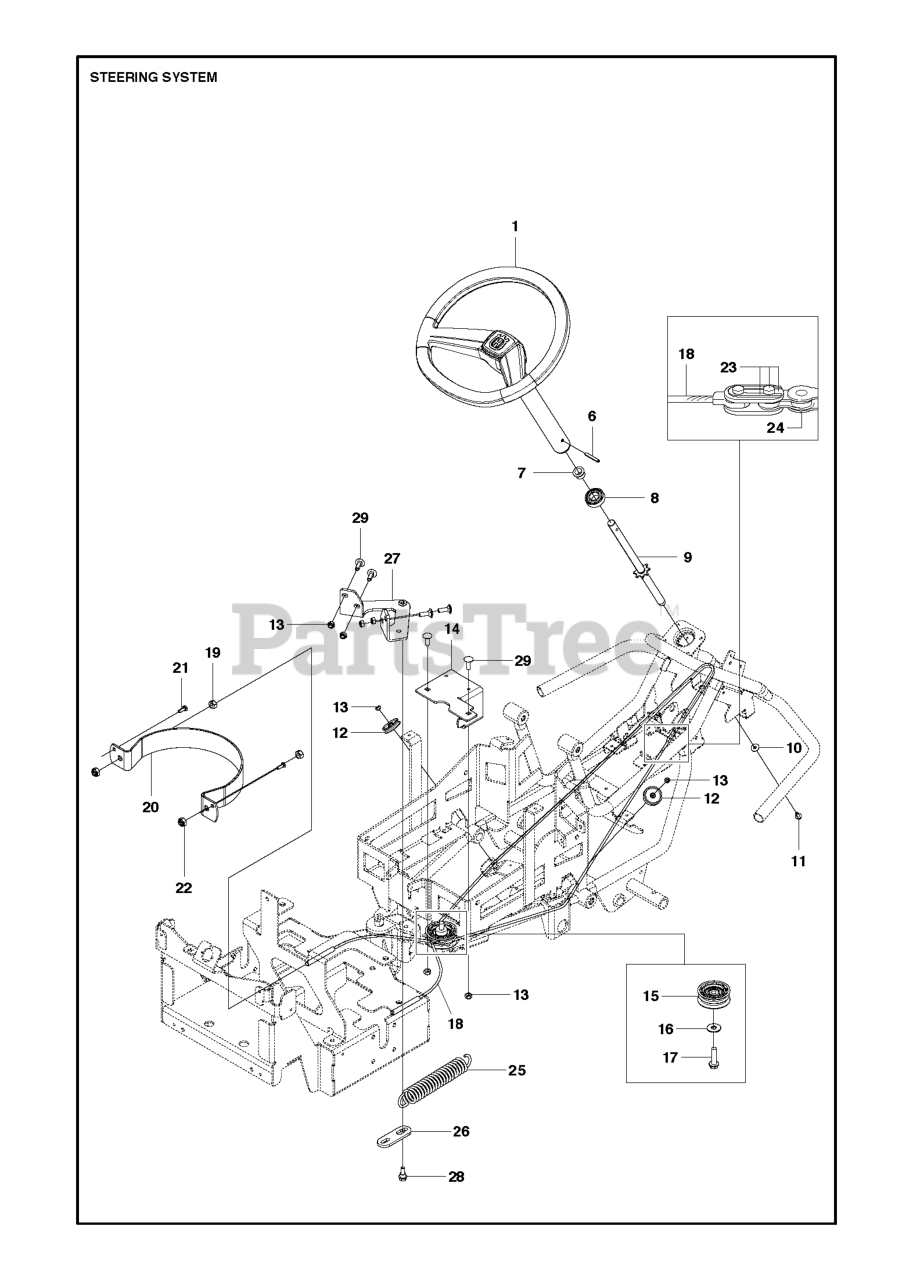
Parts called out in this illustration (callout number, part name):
1	STEERING SYSTEM
8	BALL BEARING 6004-2RS1
9	STEERING ROD
10	WASHER - 26X6.5X1.6
11	SCREW EHHFM
13	LOCKNUT M8
18	WIRE ASSY
20	GUIDE RAIL
21	SCREW
22	NUT
24	STEERING CHAIN
